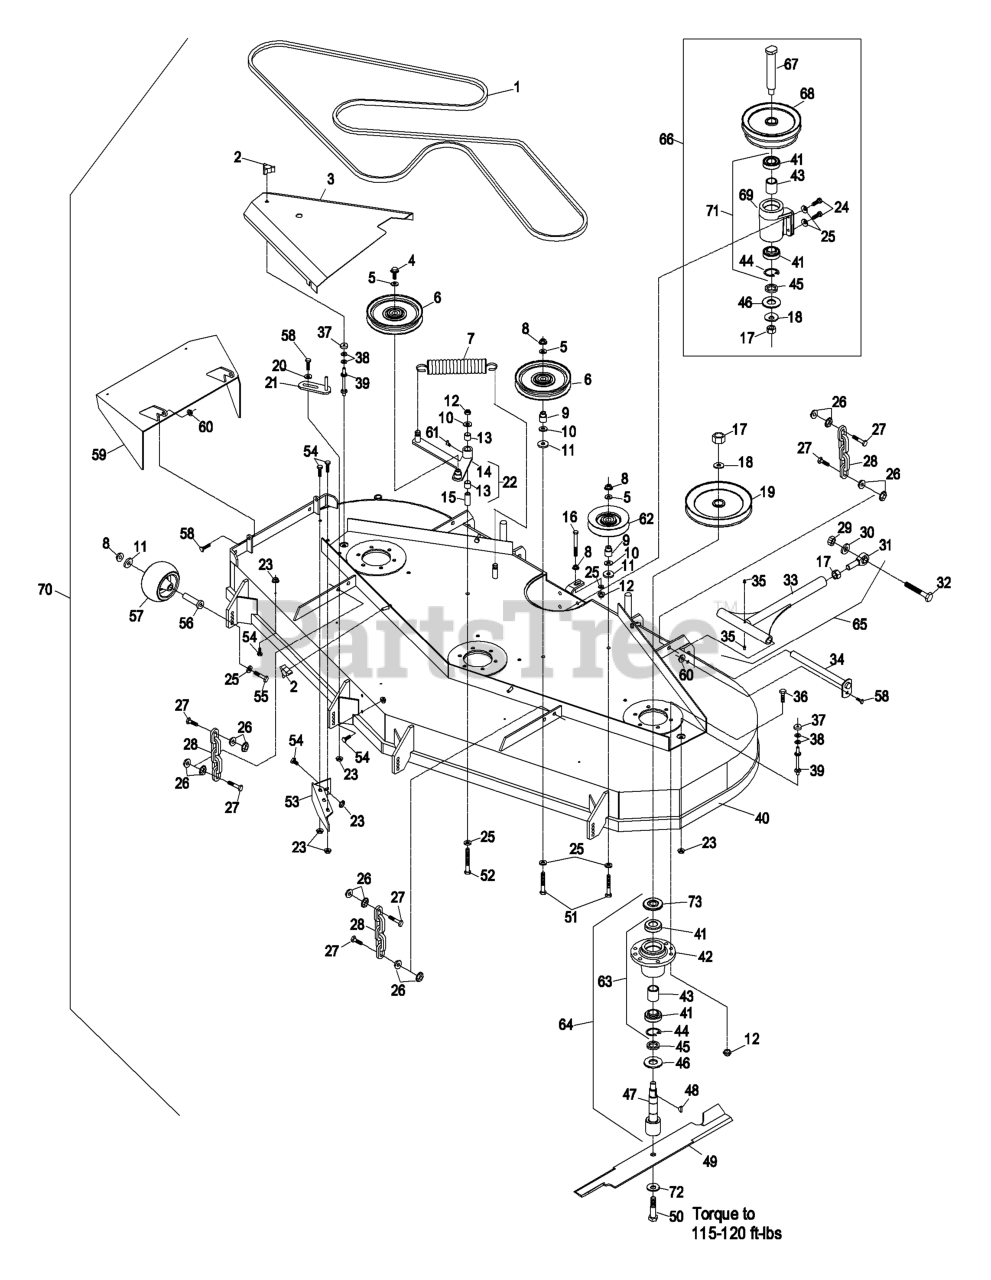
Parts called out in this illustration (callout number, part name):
1	BELT-V
2	KNOB-3 PRONG
3	SHIELD,BELT RH
4	SCREW-HHF
5	WASHER-FLAT
8	NUT-HHF, WHIZ
9	BUSHING-IDLER
10	WASHER-FLAT
12	NUT-LOCK, NI
13	SLEEVE-BEARING
15	BUSHING
16	SCREW-HH
17	NUT-HEX
18	WASHER-SPRING
19	SHEAVE,BLADE DRIVE7.5EOD
20	WASHER-SPRING
21	GUIDE-BELT
24	SCREW-HH
25	WASHER-BELLEVILLE
27	SCREW-HH
28	CHAIN-LIFT, DECK
29	NUT-HEX
30	WASHER-LOCK
31	BALLJOINT-SPHERICAL
32	SCREW-HH
34	PIN-STRUT
35	FITTING-GREASE
36	SCREW-HH
38	WASHER-FLAT
39	STUD-SHIELD, BELT (SHORT)
41	BEARING
43	SPACER-BEARING
44	RING-SNAP
45	SPACER-PULLEY/BEARING
46	GUARD-BEARING, BOTTOM
48	KEY-WOODRUFF
50	SCREW-CAP
51	SCREW-HH
52	SCREW-HH
53	WLD,BAFFLE DISCHARGE
54	SCREW-HH
55	SCREW-HH
56	BUSHING-ROLLER
57	ROLLER-SCALP, ANTI
58	SCREW-HH
59	WLD,CHUTE 72
60	Nut, 5/16-18 Nyloc
61	FITTING-GREASE, 90 DEG
62	PULLEY-IDLER
64	SPINDLE HSG ASSYCOMP72
65	ASM,STRUT SHORT
66	ASM,J-SHFTKIT60,72 3750
67	JACKSHAFT
68	SHEAVE,JACKSHAFT-DOUBLE
70	Complete Deck Assembly
72	WASHER-BLADE BOLT, HEAVY
73	GUARD,BEARING TOP .880
